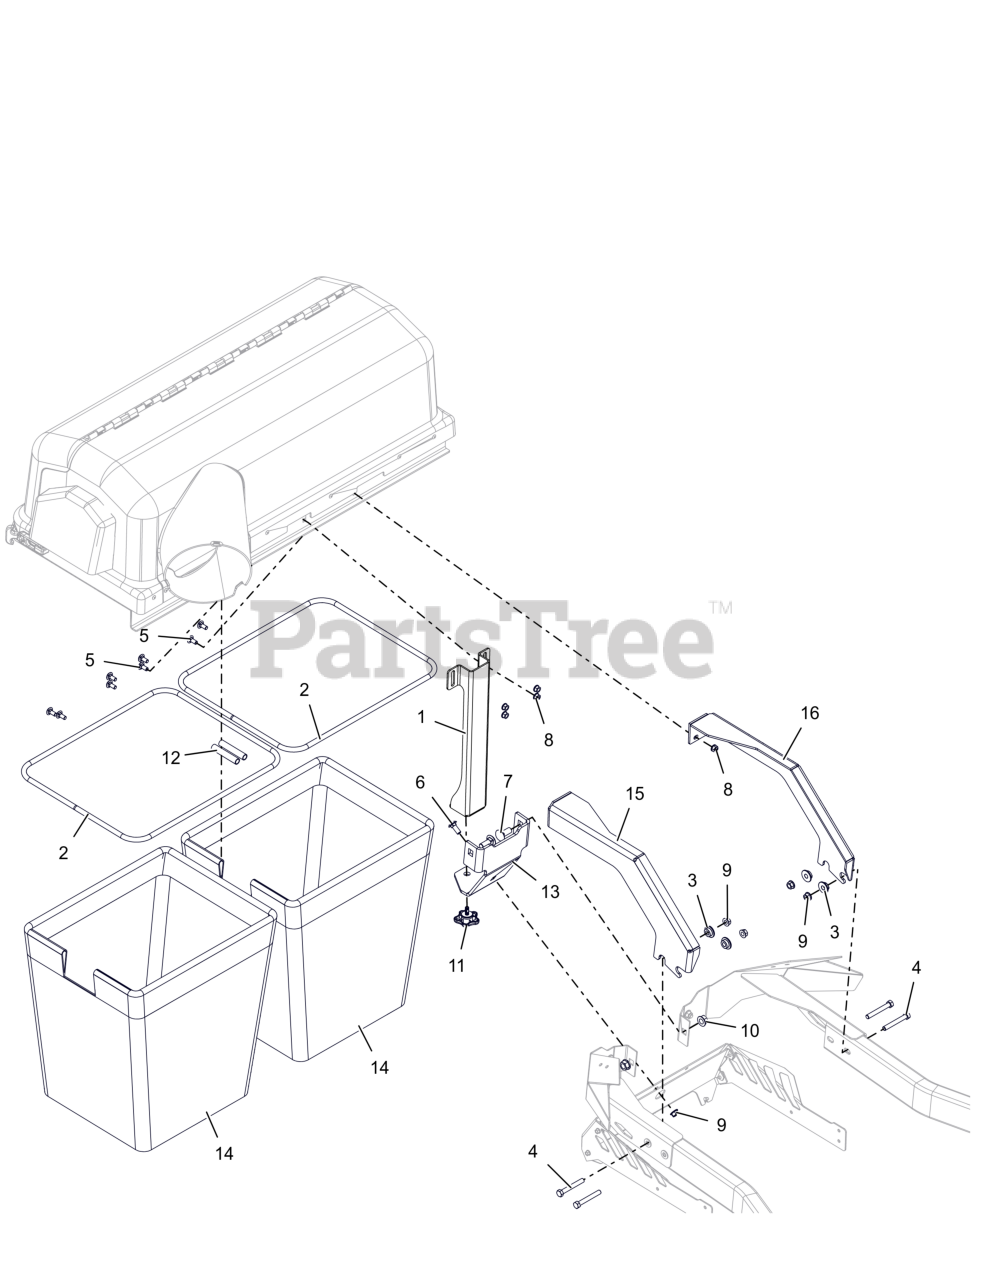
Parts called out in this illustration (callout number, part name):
1	WLDMT, BAGGER HITCH MOUNT (BLACK)
2	FRAME, BAG
3	BUSHING, FLANGE .386X.75X1.13
4	BLT, HEX .38-16X2.75 G8 ZCC
5	BLT,RHSN .31-18X.75 G5 ZCC
6	BLT, RHSN .38-16X1.00 G5 ZCC
7	BLT, RHSN .50-13X1.25 G5 ZCC
8	NUT,LK-CTR-FLG .31-18 GF ZCC
9	NUT-LK-CTR-FLG .375-16 GF ZCC
10	NUT-LK-CTR-FLG .500-13 GG ZCC
11	KNOB, WING STUDDED
12	HOSE, VINYL
13	PLATE, HITCH (BLACK)
14	BAG- MESH - 19 INCHES LONG
15	BRKT- RH BAGGER FRAME MTG
16	BRKT, LH BAGGER FRAME MNT (BLACK)
